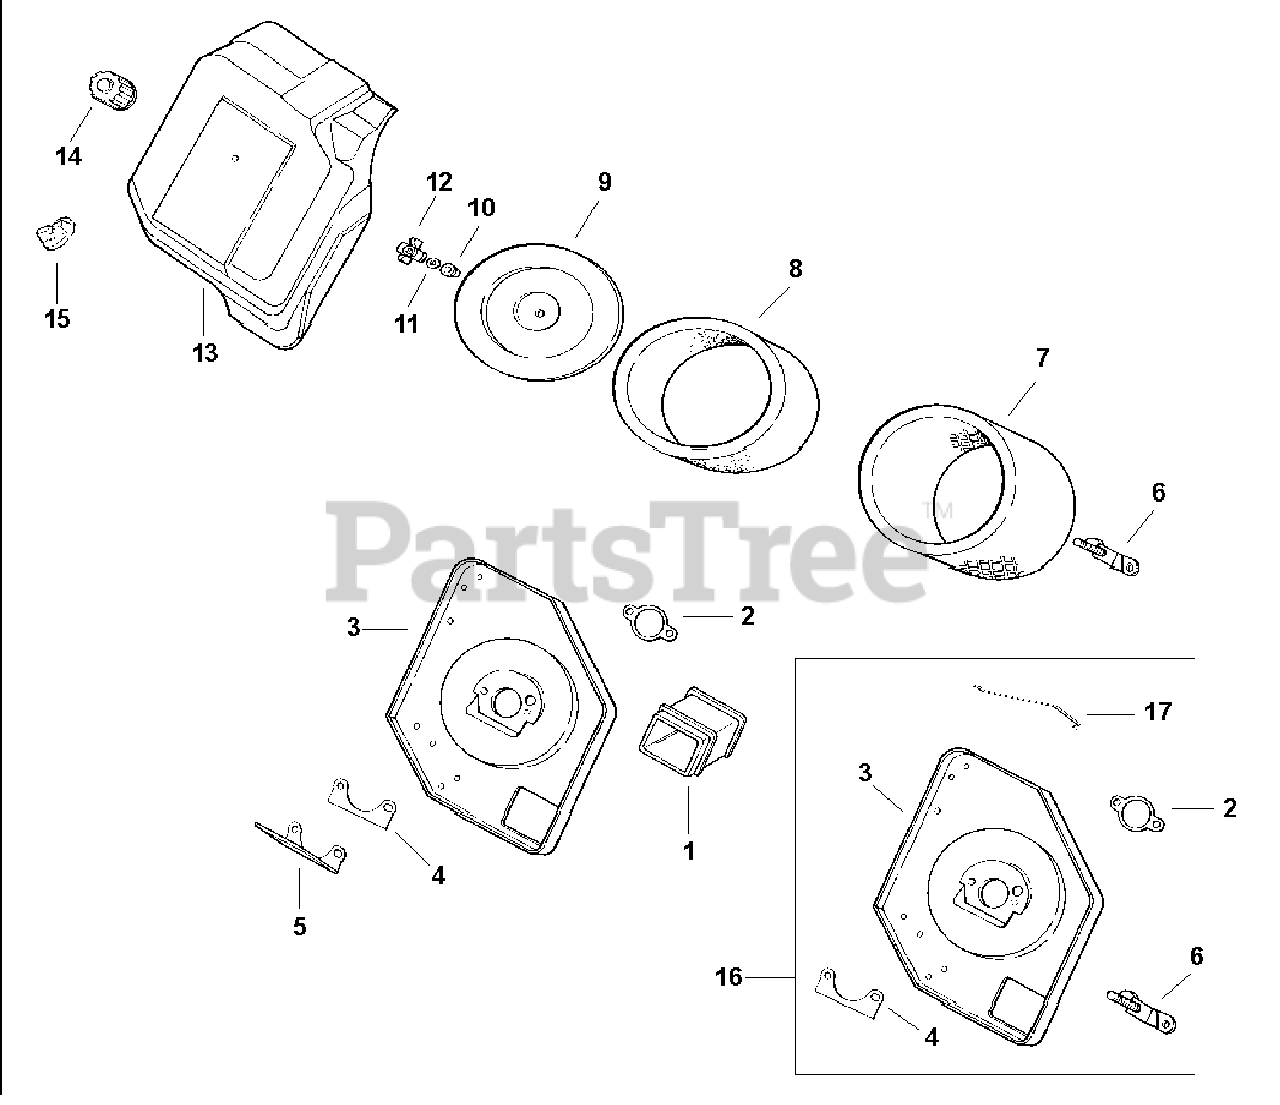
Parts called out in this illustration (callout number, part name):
2	GASKET, AIR CLEANER BASE
4	GASKET, AIR CLEANER BASE
5	KIT - USE 12 743 06
6	BRACKET, AIR CLEANER
7	ELEMENT, AIR CLEANER (KM) - Also available Retail Packaged 47 883 01-S1 Air Filter Kit
8	PRE-CLEANER
9	COVER - USE 12 743 06
10	GROMMET - (#DSC)
11	WASHER, FLAT 1/4" (O.D. 1/2")
12	NUT, WING
13	KIT - USE 12 755 66
17	LINKAGE, CHOKE
